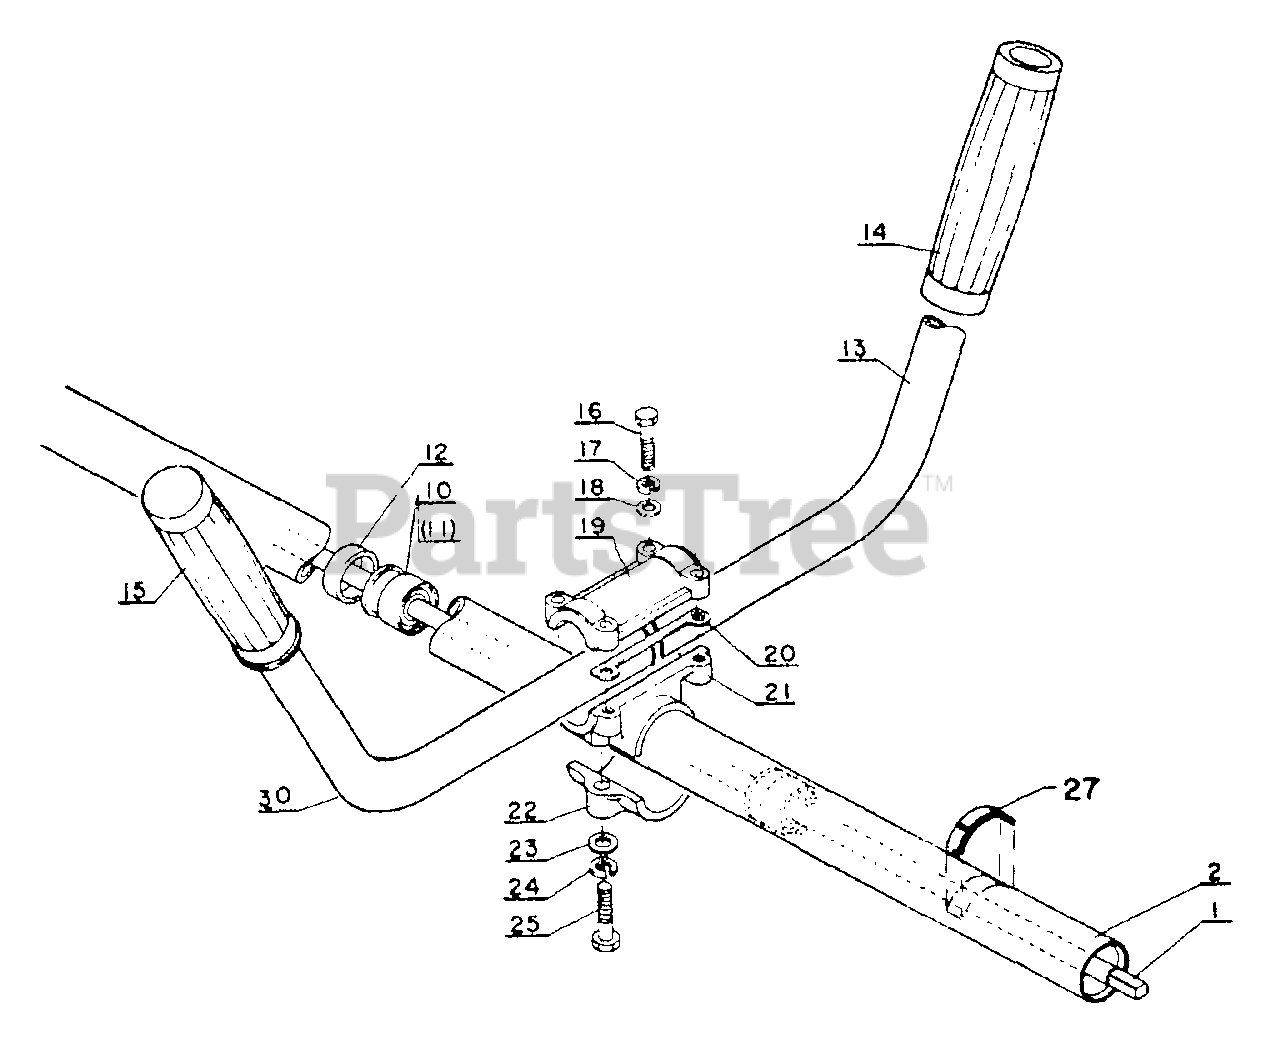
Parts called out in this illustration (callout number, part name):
1	DRIVESHAFT
2	PIPE, MAIN
13	HANDLE
14	GRIP, HANDLE
15	GRIP, HANDLE - LEFT
16	BOLT - 5X25
17	LOCKWASHER - 5
18	WASHER - 5
19	HANDLE BRACKET KIT
21	HANDLE BRACKET KIT
22	HANDLE BRACKET KIT
23	WASHER - 6
24	LOCKWASHER - 6
25	BOLT - 6X30
27	LABEL - ALIGNMENT
30	HANDLE, FRONT - LEFT
